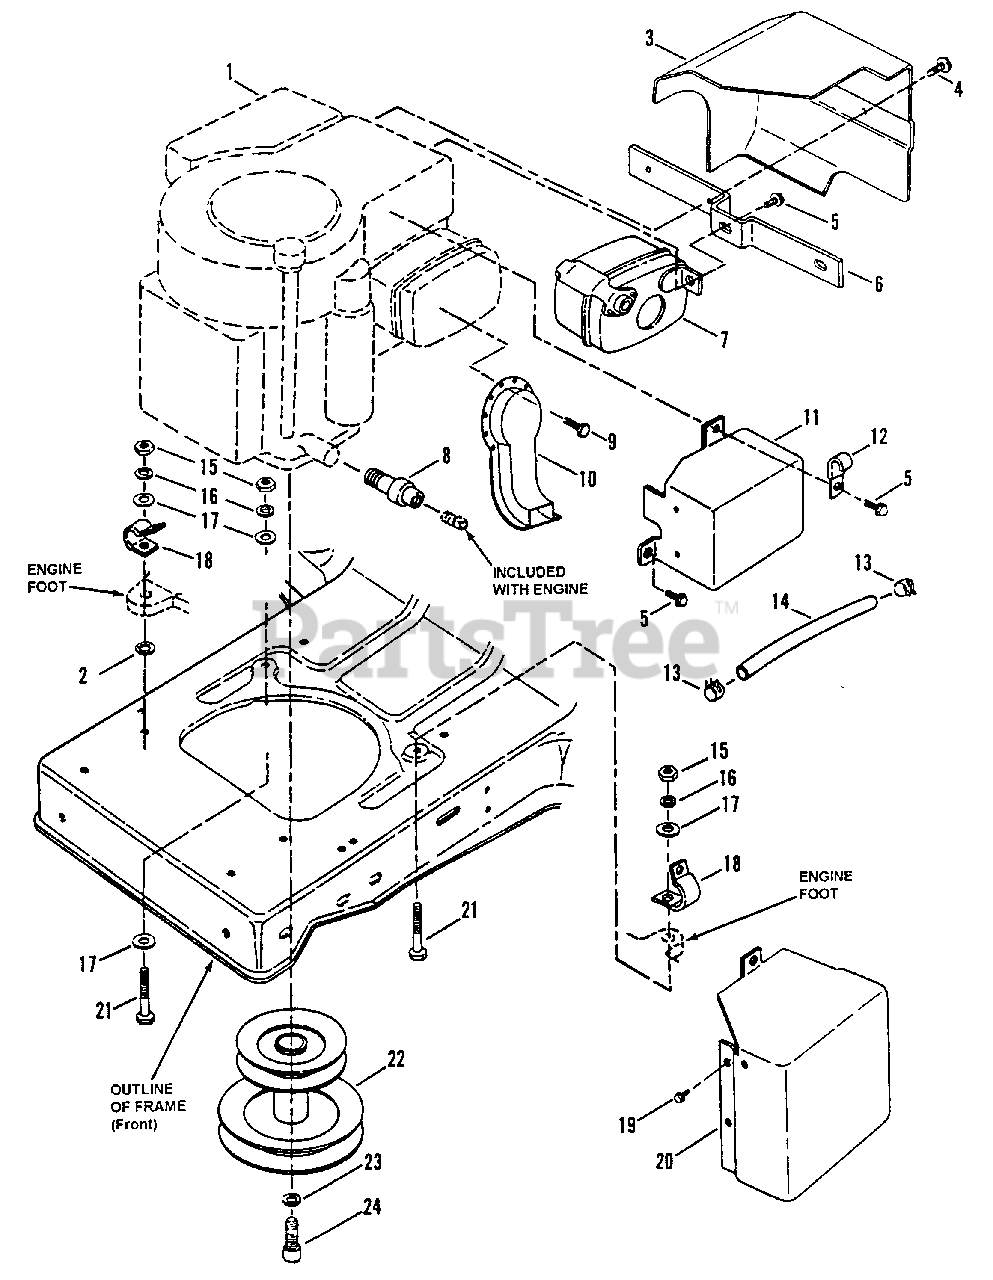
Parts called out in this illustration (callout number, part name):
2	WASHER, 5/16 Internal Tooth Lock
3	HEAT SHIELD
4	SCREW, #10-24 x 1/2" Hex Washer Self-Tap (Torx)
5	BOLT, 1/4-20 x 1/2" Hex Flange Lock, Grade 5
6	BRACKET, Heat Shield
7	MUFFLER, Exhaust
8	EXTENSION, Oil Drain
9	SCREW, #8-18 x 1/2" Hex Head, Self-Tapping
10	EXTENSION, Muffler
11	HEAT SHIELD, Muffler
12	CLIP, "J" Type
13	CLAMP, Fuel Line
14	LINE, Fuel, 14" Long
14	LINE, 7" Long
15	NUT, 5/16-18 Hex, Grade 5
16	WASHER, 5/16 Split Lock
17	WASHER, 5/16 Flat
18	CLIP, Wiring Harness
19	SCREW, #10-24 x 5/8" Hex Washer Head, Self-Tapping
20	HEAT SHIELD, Muffler
21	SCREW, 5/16-18 x 1-3/4" Hex Head Cap, Grade 5
22	ASSEMBLY, Engine Pulley
23	WASHER, 7/16 Split Lock
24	SCREW, 7/16-20 x 1" Socket Head Cap
